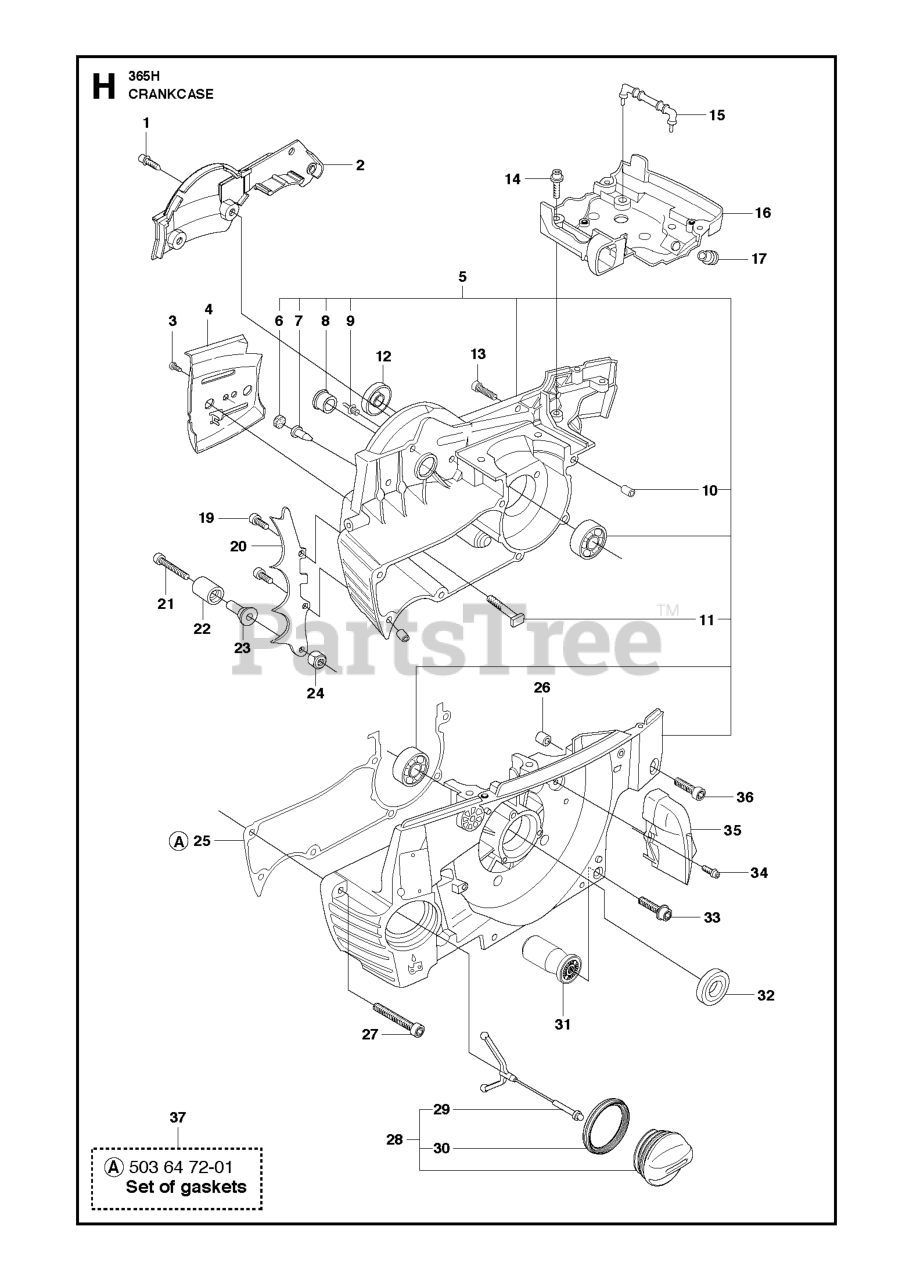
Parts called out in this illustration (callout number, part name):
1	SCREW ITXSCFM M5X12 T27 12.9
2	BLIND COVER BROMS
3	SCREW CITXPANT
5	CRANKCASE ASSY
6	PLUG
7	VALVE-CHECK (DUCKBILL)
13	SCREW ITXSCM LIMITER M5X20/8 T
14	SCREW ITXSCFM M5X12 T27 12.9
19	SCREW ITXPANM M5X16 T27 10.9
20	FELLING DOG
23	CHAIN CATCHER
27	SCREW ITXSCM M5X32.3 T27 TIP
31	ANTIVIBE ELEMENT
33	SCREW
34	SCREW ITXSCFM M5X12 T27 12.9
36	SCREW ITXSCM M5X20 T27 10.9 Z
37	GASKET SET
